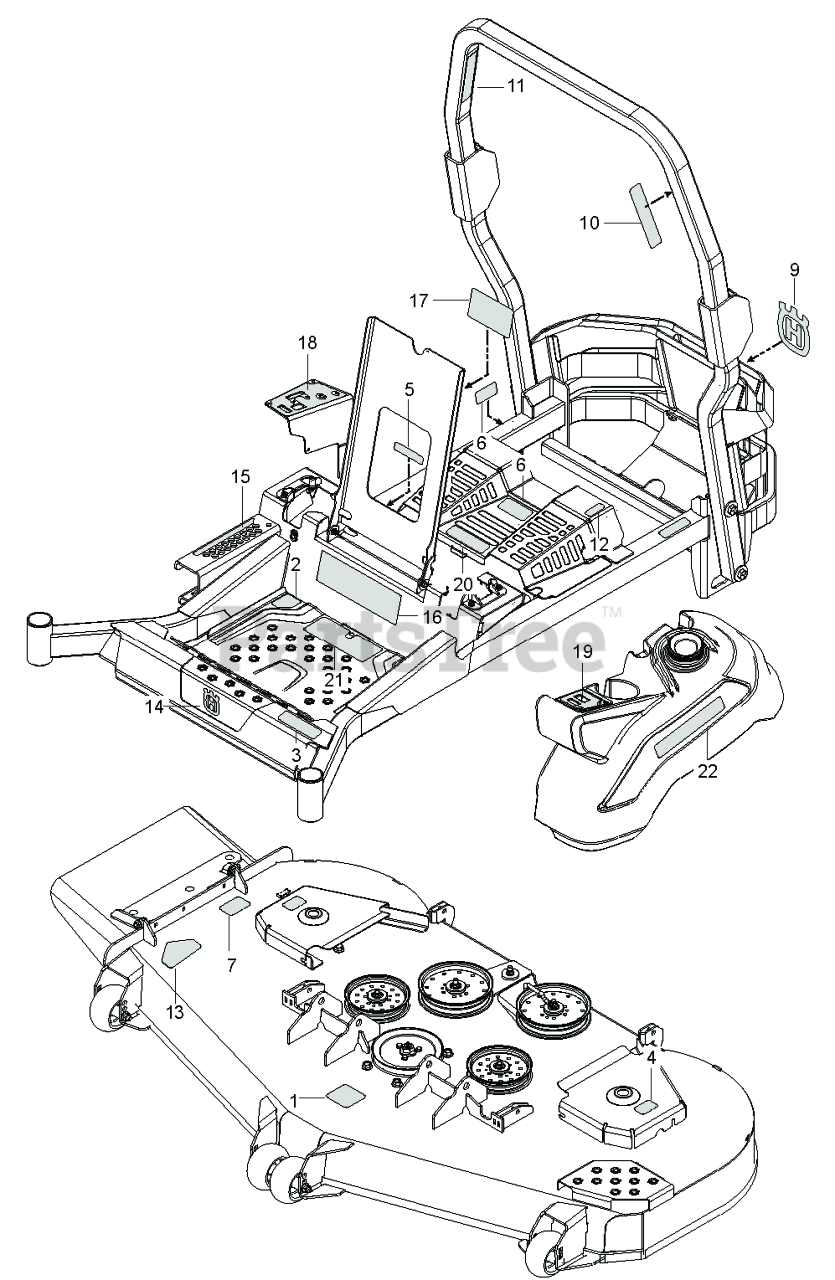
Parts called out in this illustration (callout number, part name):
1	DECAL, BELT ROUTING
1	DECAL, 72" BELT ROUTING
2	DECAL.ZTR.SADLE.WARN.PZ500.ENG
3	DECAL.ZTR.PZ500SERIES.Z554X
4	DECAL.DECK.6MIL.EURO.NOSTEP
5	EURO DECAL-BATTERY WARNIN6
6	DECAL, BELT DRIVE
7	DECAL.DECK.6MIL./DEF.SHLD.WARN
9	DECAL, CROWN H, 110MM
10	DECAL ROPS DECAL DECAL.ROPS.PZ
11	DECAL, ROPS, WARNING
12	DECAL, FUSE
13	DECAL, DECK DEFLECTOR, WARNING
14	DECAL.BADGE.55MM.CROWNH.HUSQ
15	DECAL.PZ500.DECKLIFT.HUSQ
16	DECAL.ZTR.SADDLE.COMM.PZ500
17	DECAL.PZ500.MAINTANCE/SVC.2018
18	DECAL.ZTR.CONTRPANEL.PZ500.EFI
19	DECAL.ZTR.CONTROLPANL.PZ500.LH
20	DECAL.ZTR.TRANCOVER.WARN.PZ500
21	DECAL.ZTR.SADLE.WARN.PZ500.ENG
22	DECAL.HUSQVARNA.210MM
